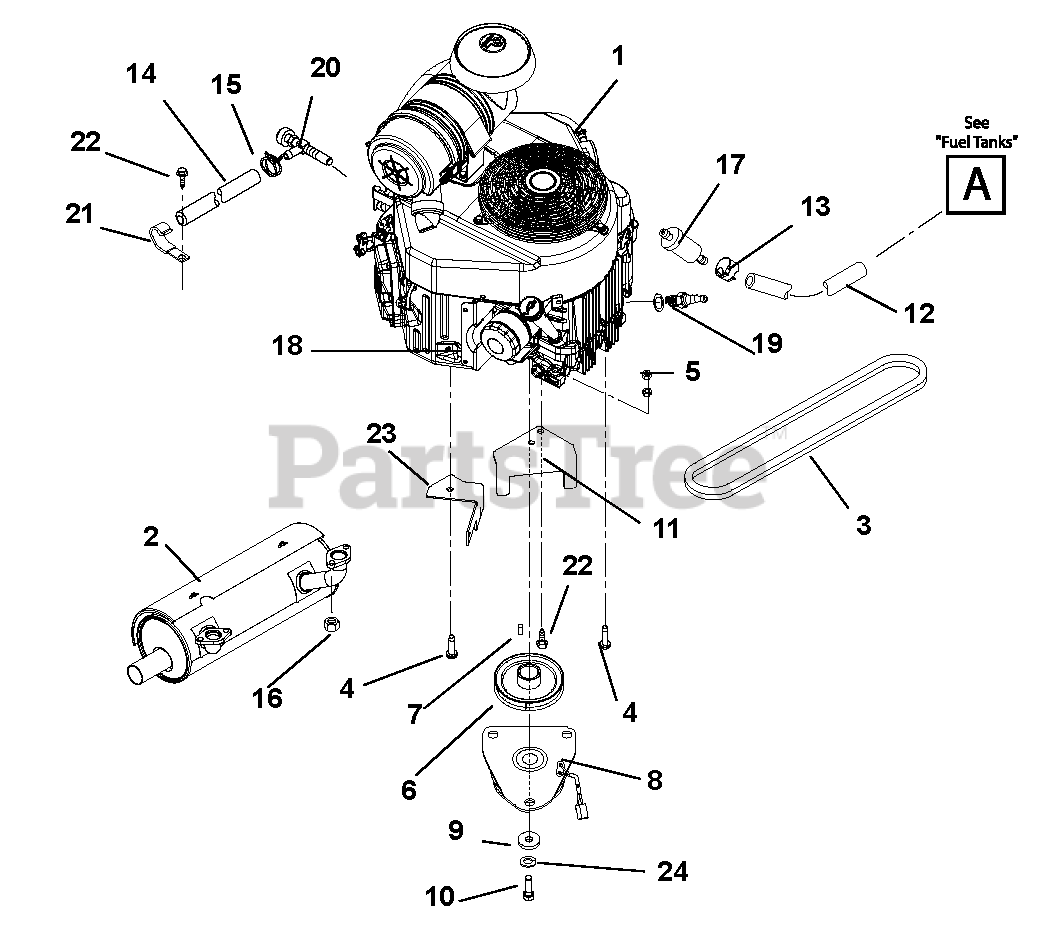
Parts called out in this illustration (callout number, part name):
1	Engine, Kawasaki Fixed 481
2	Muffler, Kawasaki
3	V-Belt, 53.7 Inches
4	Screw, Tapping Hex Washer Head .38-16 x 1.50
5	Nut, Locking Nylon Flange .31-18
6	Pulley, 4.50 OD x 1.127 Engine
7	Key, Square .25 x .625 x .25 SAE 8630 OR SAE 1035
8	Clutch, Ogura
9	Washer, Flat Steel .463 x 1.375 x .250
10	Bolt, Hex .44-20 x 1.50 Grade 5 EP80
11	Anchor, Ogura Clutch
12	Hose, Gas Line .25" I.D.
13	Hose, Clamp
14	Hose, .50 x 6.00
15	Clamp, .88 Diameter Hose
16	Nut, Top Lock M8-1.25
17	Fuel Filter, Kawasaki
18	Oil Filter, Kawasaki
19	Spark Plug, Kawasaki
20	Drain, .50 Oil
22	Screw, Tapping .38-16 x .75 Hex Washer Head
23	Guard, Clutch Wire
24	Washer, Locking .44
